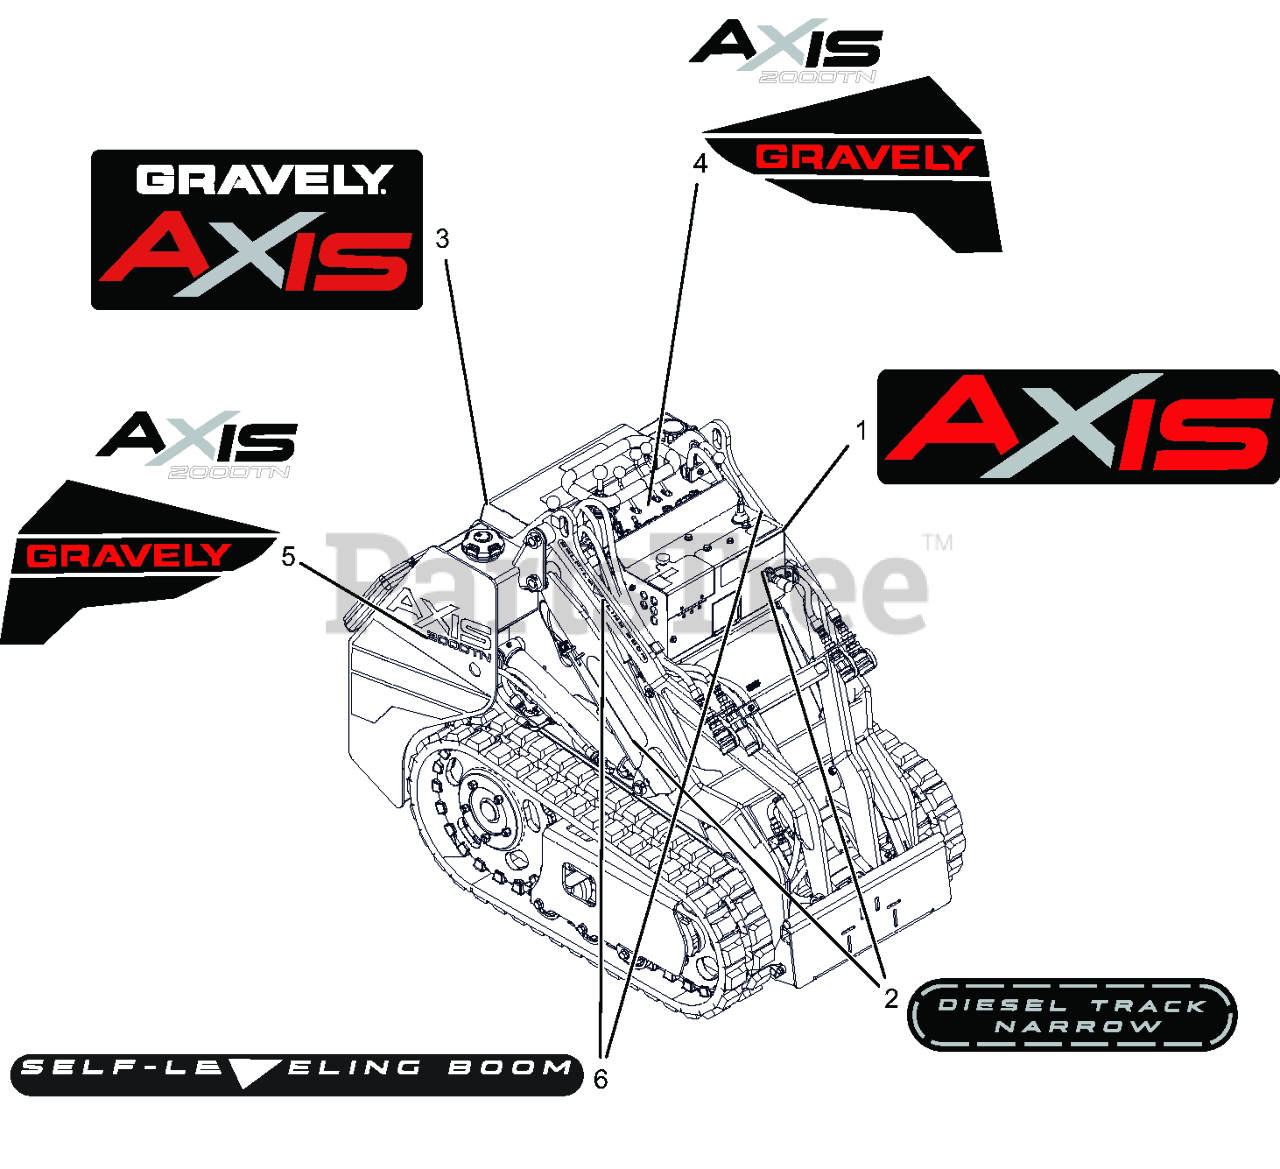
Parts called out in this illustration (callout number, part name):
1	DECAL, AXIS FRONT
2	DECAL, DIESEL TRACK NARROW
3	DECAL, AXIS REAR
4	DECAL, 200 DTN LEFT
5	DECAL, 200 DTN RIGHT
6	DECAL, SELF LEVELING
